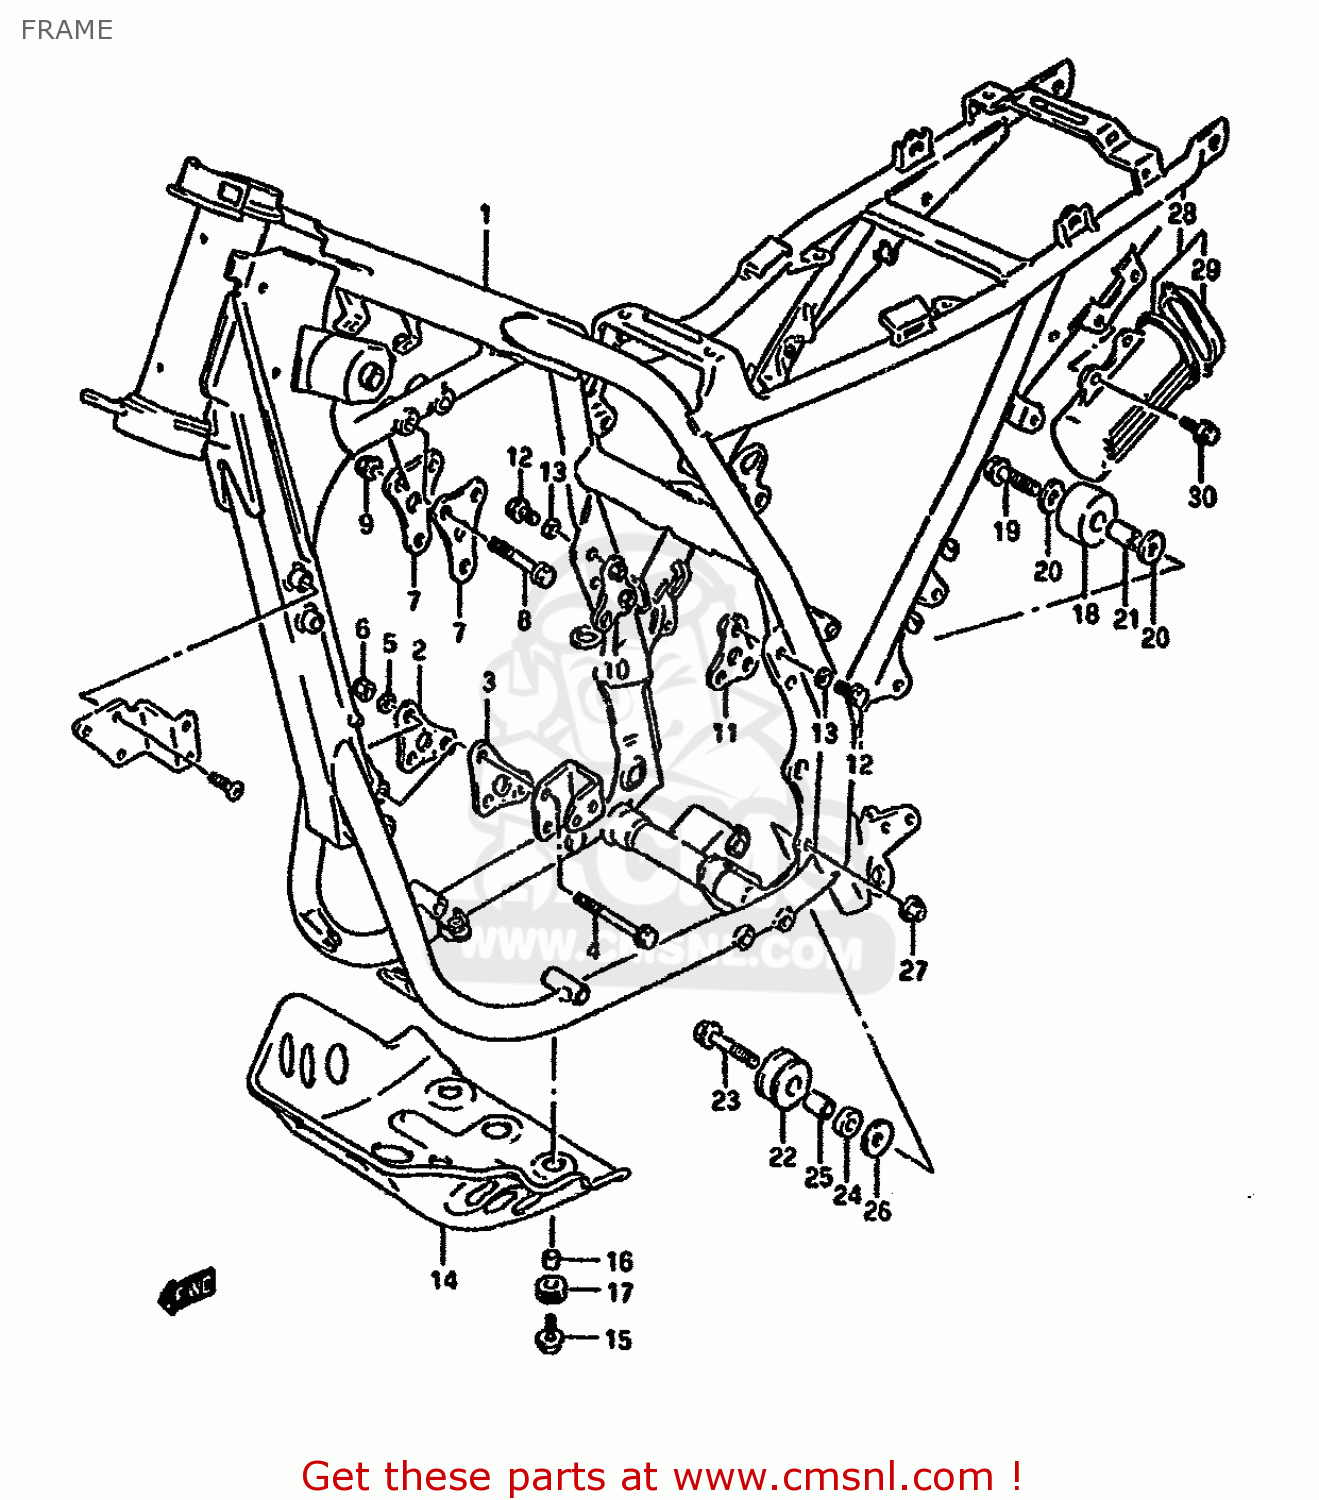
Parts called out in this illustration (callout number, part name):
1	FRAME
2	PLATE,ENG MTG FR,R
3	PLATE,ENG MTG FR,L
4	BOLT(8X72)
5	LOCK WASHER
6	NUT
7	PLATE,ENGINE MOUNTING
8	BOLT(8X50)
9	NUT
10	PLATE,ENG MTG RR,R
11	PLATE,ENG MTG RR,L
12	BOLT(8X20)
13	LOCK WASHER
14	PROTECTOR,ENGINE
15	BOLT 6X20
16	SPACER (7X9X7)
17	CUSHION
18	ROLLER,CHAIN CONTROL
19	BOLT(8X41)
20	WASHER (8.2X24X1.6)
21	SPACER (8.6X13.8X28)
22	ROLLER,CHAIN CONTROL
23	BOLT 8X50
24	SPACER,LOWER
25	SPACER(8.6X12X25.5)
26	WASHER
27	NUT
28	HOLDER,TOOL
29	CAP,HOLDER
30	BOLT(6X16)
